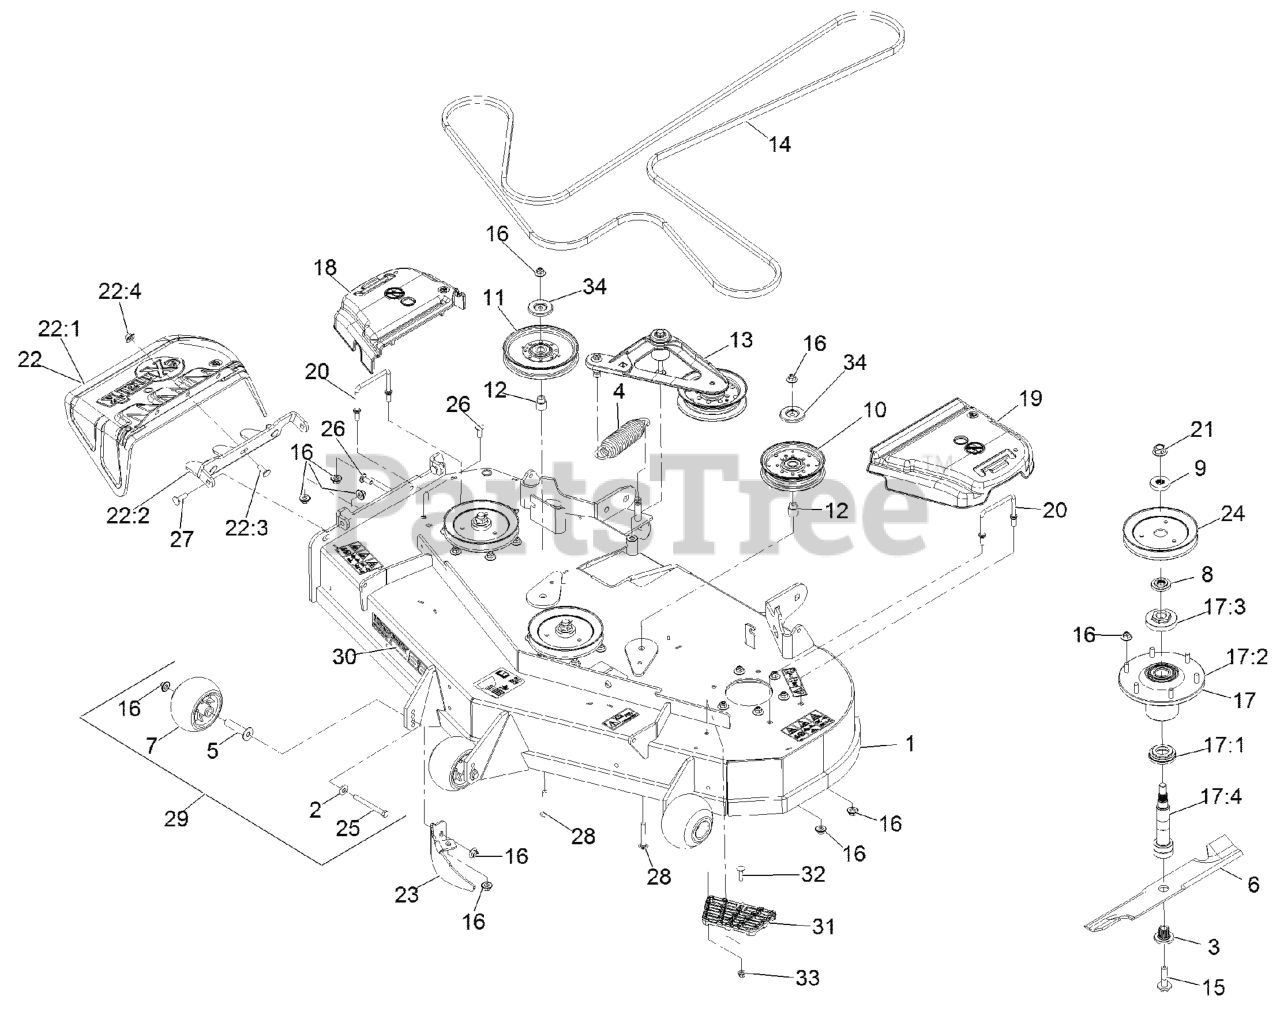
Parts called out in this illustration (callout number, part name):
1	ASM,DECK W/ DECALS 52
2	WASHER-BELLEVILLE
3	BUSHING,SPLINED
4	SPRING-EXTENSION
5	AXLE, ROLLER
7	ROLLER-SCALP, ANTI
8	SPACER,SPLINED STEPPED
9	SPACER,SPLINED
10	PULLEY-IDLER, FLAT
11	IDLER-PULLEY
12	BUSHING-IDLER
13	DECK IDLER ASM
15	SCREW,SEMS 1/2-20 X 2.19
16	Nut-Nyloc 3/8-16 Flg
17	ASM,SPINDLE HOUSING
17:1	GUARD,BOTTOM
17:2	ASM,CUTTER HOUSING
17:3	NUT, SPINDLE 7/8-14
17:4	SPINDLE,DOUBLE SPLINE
18	COVER-BELT, RH
19	COVER-BELT, LH
20	WIREFORM-COVER
21	NUT-FLANGE, CENTERLOCK
22	ASM,DISCHARGE CHUTE
22:1	CHUTE,DISCHARGE
22:2	BRACKET,DISCHARGE CHUTE
22:3	SCREW-CARR
22:4	Nut-Nyloc 3/8-16 Flg
23	BAFFLE-DOGLEG, LZ-VT52
24	SHEAVE,BLADE DRIVE
25	SCREW-HH 3/8-16 X 3 3/4 GR 8
26	SCREW-CARR
27	Bolt-Carriage 3/8-16 X 1 1/4
28	SCREW-CARR
29	KIT, ANTI-SCALP ROLLER
30	Decal, 526
31	STEP-DECK
32	Bolt-Carriage 5/16-18 X 1 1/4
33	NUT-HF, NI
34	SHIELD-DUST
